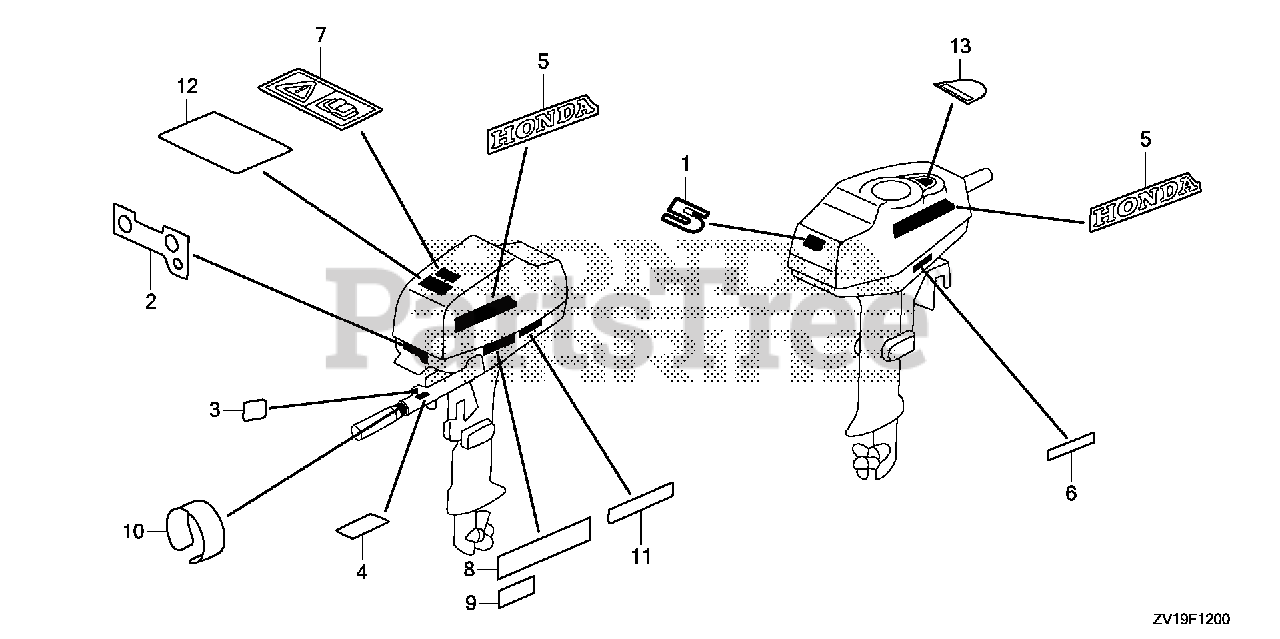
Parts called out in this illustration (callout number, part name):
1	MARK, RR. (5)
2	LABEL, INDICATION
3	MARK, EMERGENCY SWITCH INDICATION (EU)
4	MARK, SPARE CLIP (ENGLISH)
5	MARK, SIDE STRIPE (HONDA)
6	MARK, CHANGE (JAPANESE/ENGLISH)
8	LABEL, OIL CAUTION (ENGLISH)
10	MARK, THROTTLE (ENGLISH)
11	LABEL, STORING CAUTION (ENGLISH)
12	LABEL, CAUTION OPERATOR (ENGLISH)
13	MARK, EMERGENCY START (E)
